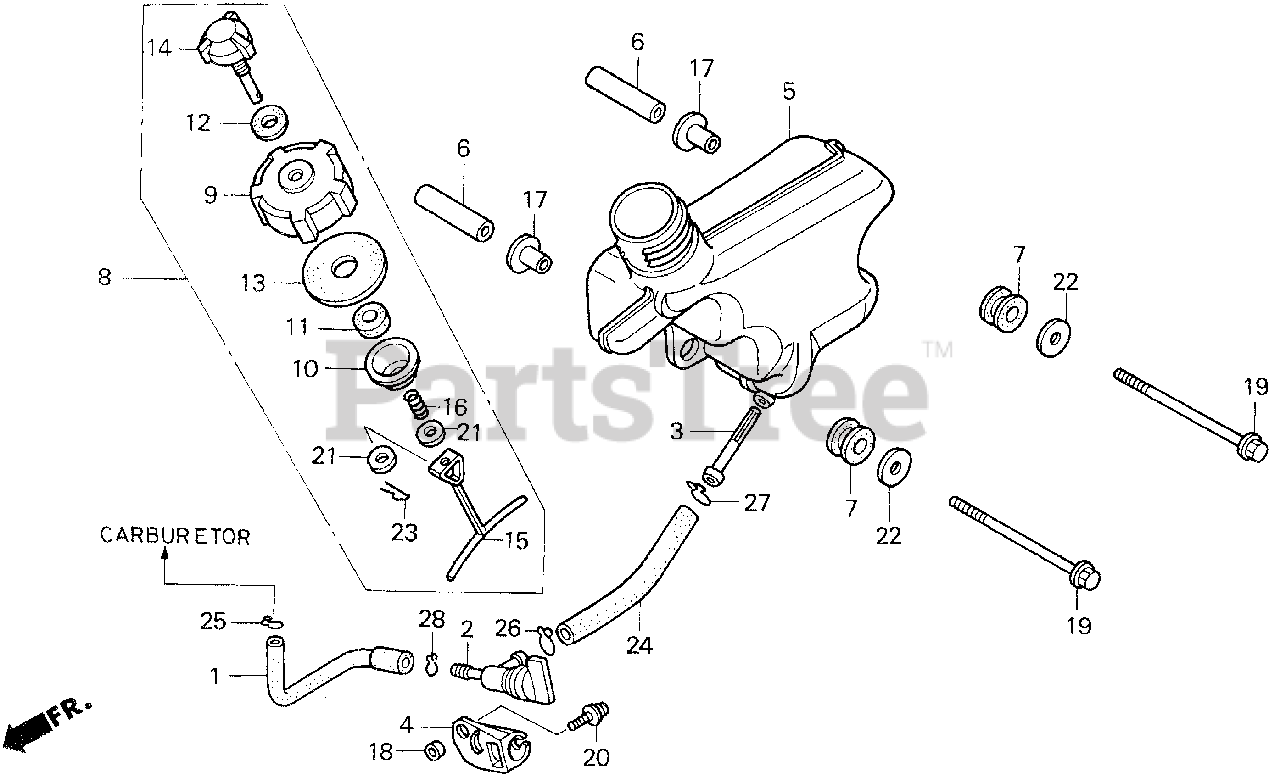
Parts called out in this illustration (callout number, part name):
1	TUBE B, FUEL
2	PETCOCK ASSY. (MAN)
3	FILTER, FUEL
4	BRACKET, PETCOCK
5	TANK, FUEL
6	COLLAR, TANK SETTING
7	RUBBER A, TANK MOUNTING
8	CAP ASSY., FUEL TANK
9	BODY, FUEL CAP
10	INNER, FUEL CAP
11	SPONGE, FUEL CAP BREATHER
12	GASKET, VALVE
13	GASKET, FUEL CAP
14	VALVE, BREATHER
15	LINK, FUEL CAP
16	SPRING, FUEL CAP
17	COLLAR, CANISTER MOUNT
18	COLLAR, FR. TURN SIGNAL
19	BOLT, FLANGE (6X65)
20	SCREW-WASHER (5X10)
21	WASHER, FLAT (4MM)
22	WASHER, PLAIN (6MM)
23	PIN, LOCK (4MM)
24	BULK HOSE, FUEL (7.5X8000) (7.5X65)
25	CLIP, TUBE (B8)
26	CLIP, TUBE (B12)
27	CLIP, TUBE (B12.5)
28	CLIP, TUBE (C9)
